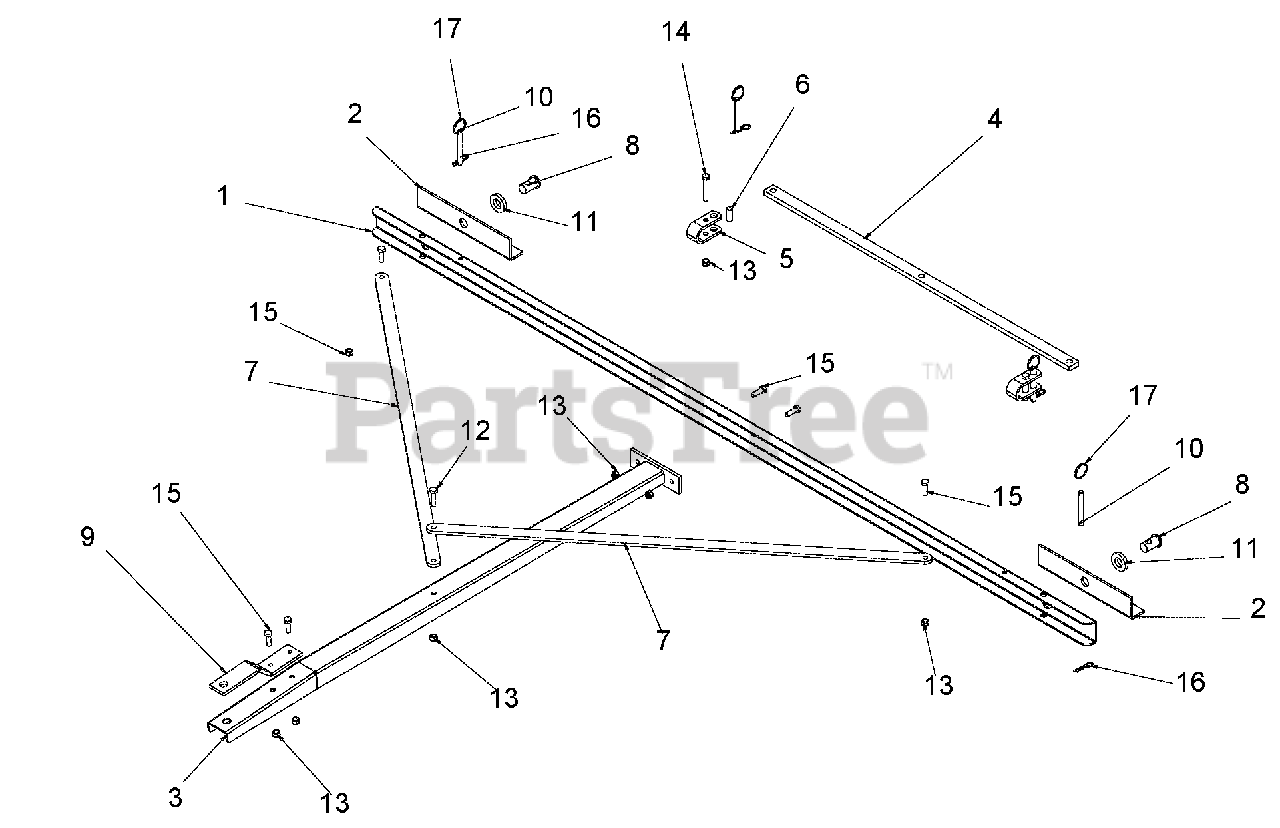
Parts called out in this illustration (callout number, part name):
1	Draw Bar
3	Tongue Weldment
6	Bushing, .437 OD x 1.00
8	Swivel Pin
10	Pin, Hitch
11	Washer, Flat Steel .812 x 1.5 x .135 YWZC
12	Bolt, 5/16-18 x 1.25 Grade 5
13	Nut, Nyloc 5/16-18
14	Bolt, 5/16-18 x 2 Grade 5
15	Bolt, 5/16-18 x 1 Grade 5
16	Pin, Hair
17	Ring, Retaining
